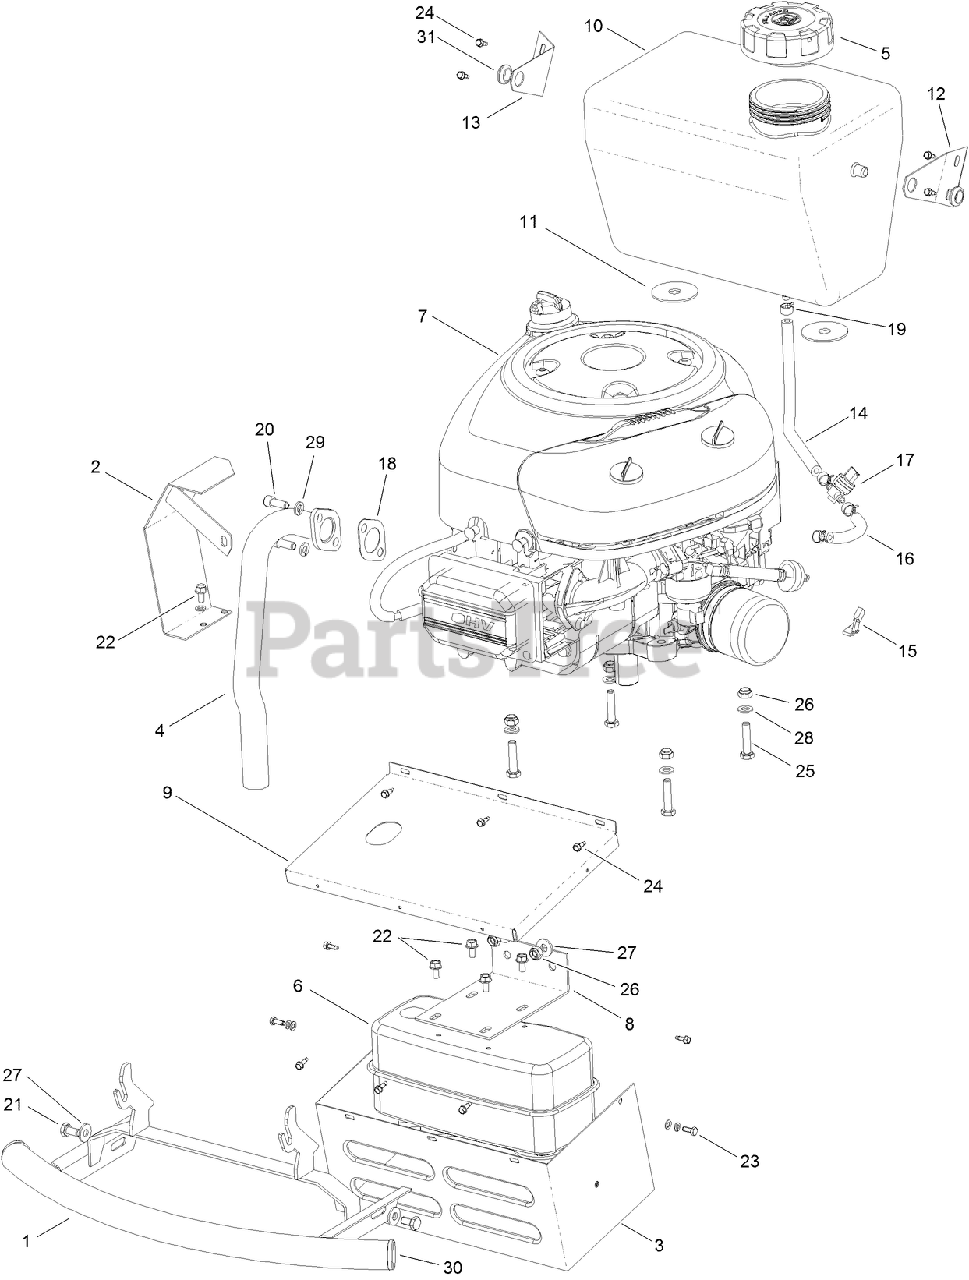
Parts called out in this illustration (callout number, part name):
1	BUMPER
2	SHIELD-EXHAUST TUBE
3	SHIELD-MUFFLER
4	TUBE-EXHAUST
5	CAP-FUEL
6	MUFFLER
8	BRACKET-MUFFLER MOUNT
9	COVER-TOP
10	TANK-FUEL
11	WASHER-RUBBER
12	BRACKET-FUEL TANK, LEFT
13	BRACKET-FUEL TANK, RIGHT
14	HOSE-FUEL
15	REDUCER-THROTTLE, RPM
16	LINE-FUEL
17	VALVE-TANK, FUEL
18	GASKET
19	CLAMP-LINE, FUEL
20	SCREW-HH
21	SCREW-HH
22	SCREW-HH
24	SCREW-TAP
26	NUT-LOCK, NI
27	WASHER-PLAIN
28	WASHER-PLAIN
29	WASHER-SPRING
30	CAP-BUMPER
31	BUSHING
